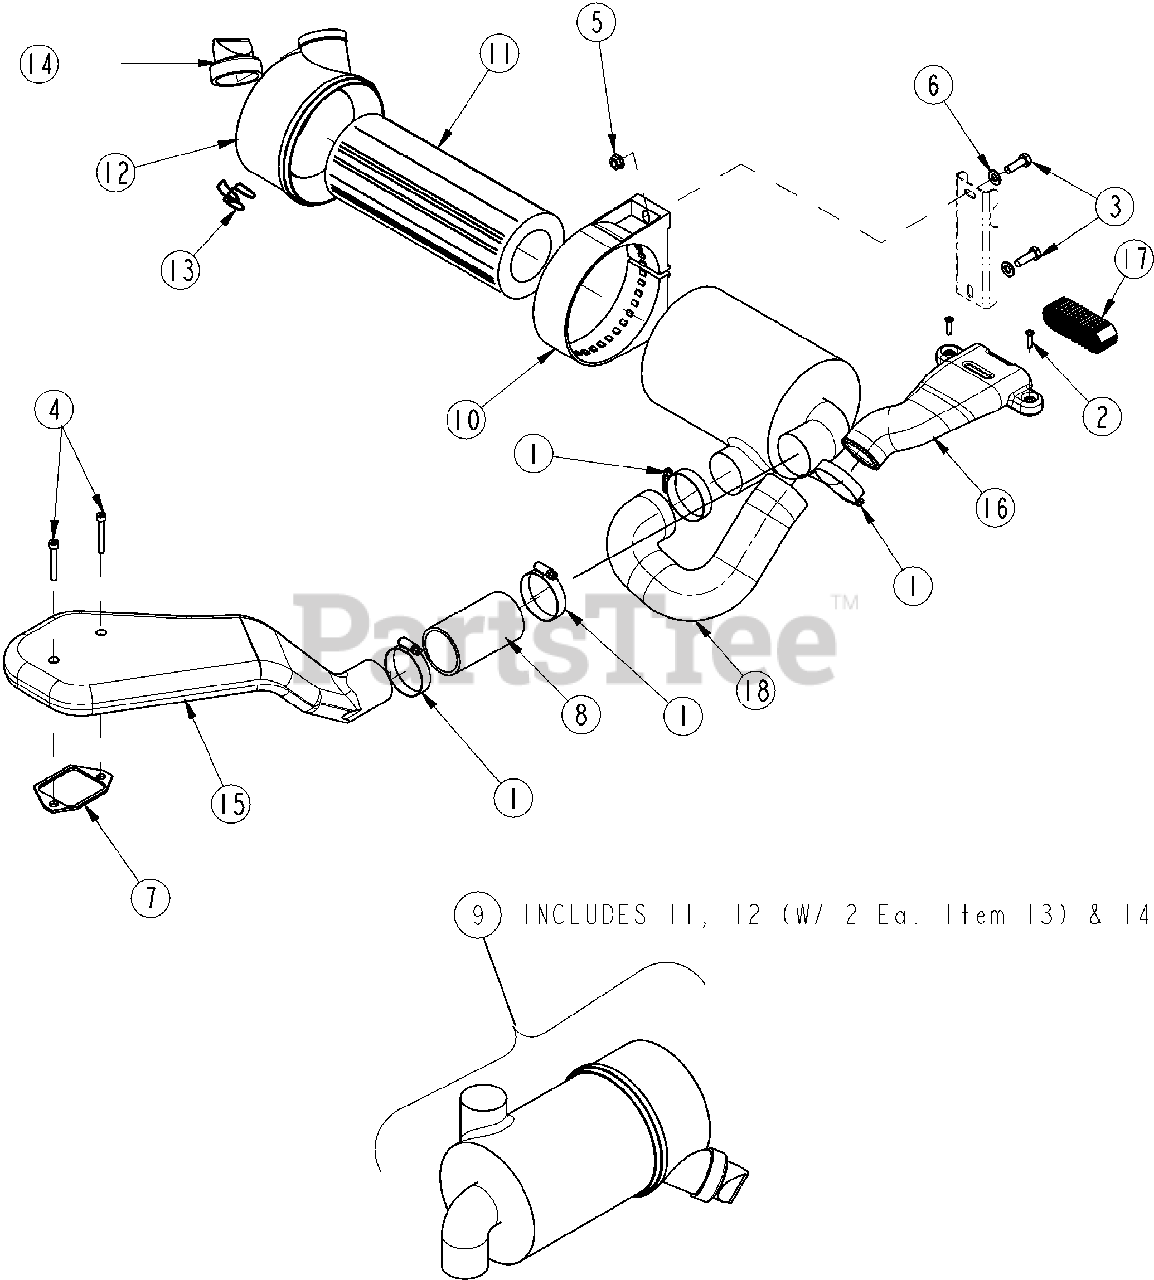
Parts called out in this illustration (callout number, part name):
1	CLAMP WRM DRV#36SS (1.81-2.75)
2	SCR SELF TAP #10 X 3/4
3	BOLT, HEX 5/16-18 X 1 GR5 ZNYCR
4	HSHCS M6X1X45 GR8.8
5	NUT, HEX TOP LOCK FLANGE 5/16-18
6	WASHER, FLAT 5/16 HARD ASTMF44712
7	GASKET-ENGINE AIR INTAKE TRUCK
8	HOSE, 2" ID X 4" LONG
9	DNLDSN AC ASSY W/FLTR G057514
10	DNLDSN AIR CLNR CLAMP PPGF30
11	FILTER AIR OUTER ELEMENT
12	DNLDSN COVER W/LATCHES P533761
13	DNLDSN LATCH P538928
14	DNLDSN VACUATOR (BURP) P522958
15	AIR INTAKE PLASTIC ST TRUCK
16	SNORKEL AIR INTAKE
17	FILTER, AIR INTAKE
18	HOSE AIR INTAKE
